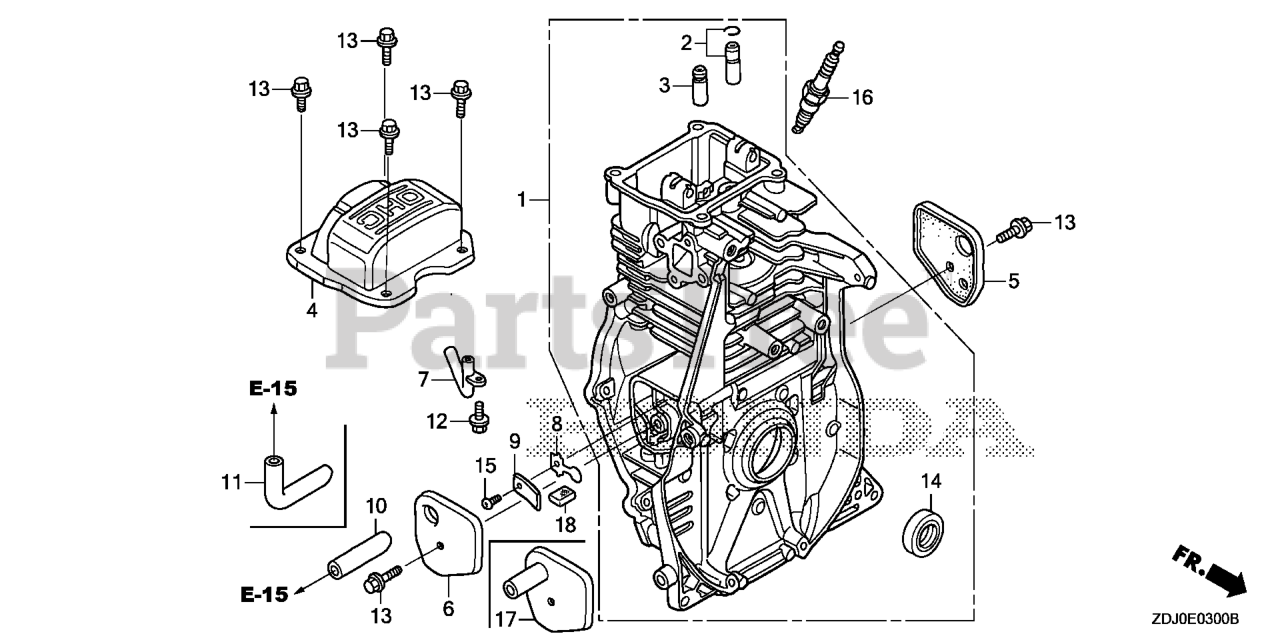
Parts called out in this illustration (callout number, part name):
1	CYLINDER ASSY.
4	COVER, HEAD
5	COVER A, BREATHER
6	COVER B, BREATHER
8	VALVE, OIL OUTLET
9	PLATE, STOPPER
10	TUBE, BREATHER
13	BOLT, FLANGE (6X14)
14	OIL SEAL (22X35X6)
15	SCREW, PAN (3X5)
16	SPARK PLUG (U16FSR-UB) (DENSO)
16	SPARK PLUG (CR5HSB)
